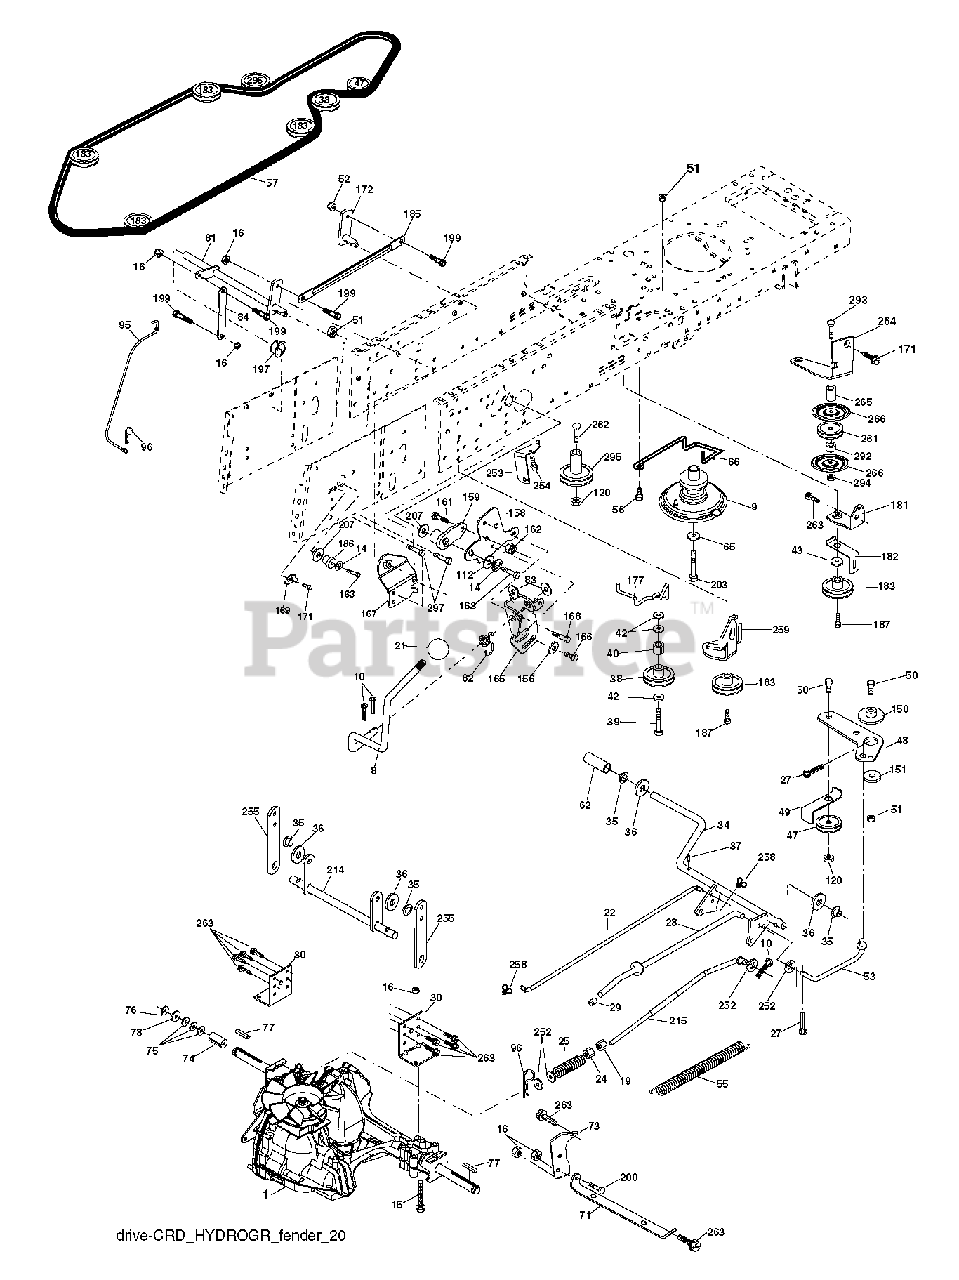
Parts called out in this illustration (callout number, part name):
8	ROD SHIFT FENDER ADJUST LT
14	LOCKWASHER
15	BOLT HEX 5/16-18 GR 5
16	NUT.71038.31-18.HEX.NYLOCK
19	NUT
21	KNOB.DELUXE.(PISTOL.GRIP).BLAC
24	NUT
27	COTTER PIN
28	ROD, PARKING BRAKE
30	BRKT, TRNSXLE MNT 20"
34	SHAFT, FOOT PEDAL
35	BEARING.NYLON
37	DRIVE PIN
42	WASHER
47	IDLER PULLEY
48	BELLCRANK, CLUTCH
50	BOLT.3/8-16X1.50
51	LOCKNUT
52	LOCKNUT
53	LINK.CLUTCH.7.66.2005
55	SPRING, RETURN LT
57	V-BELT 113"
62	PEDAL COVER T
65	LOCKWASHER
66	KEEPER BELT ENGINE
71	STRAP TORQUE LH HYDRO
73	STRAP TORQUE RH HYDRO
81	SHAFT ASSY
83	WASHER
84	LINK.PNT.TRANSAXLE.0510.CRD
96	RETAINER M
112	WASHER LT
120	NUT LOCK FLG 3/8-16 UNC
150	BUSHING.BELLCRANK.GRD.DR
151	WASHER 12/32X2X10GA
156	WASHER.SRRTD.5/16
158	BRACKET.SHIFT.MOUNT
159	HUB.SHIFT
161	BOLT
162	NUT.CROWNLOCK.1/4
165	BRACKET.PIVOT.LEVER
167	BRACKET
168	BOLT.SHOULDER.5/16-18X
169	PLATE.FASTENING.CROSS.SHAFT
183	PULLEY.V-IDLER.
187	BOLT.5/16-18X1.25
197	NYLINER SNAP 5/8" ID
199	BOLT SHOULDER 5/16-18 UNC
200	BOLT
203	BOLT.HEX.7/16-20x5
252	WASHER
254	SCREW 3/8-16X1
258	CLIP RETAINER
261	FLAT IDLER PULLEY
263	SCREW, 3/8-16X3/4
294	NUT, HEX 3/8-16
295	PULLEY IDLER COMPOSITE
297	SCREW LT.3/8-46X5/8
